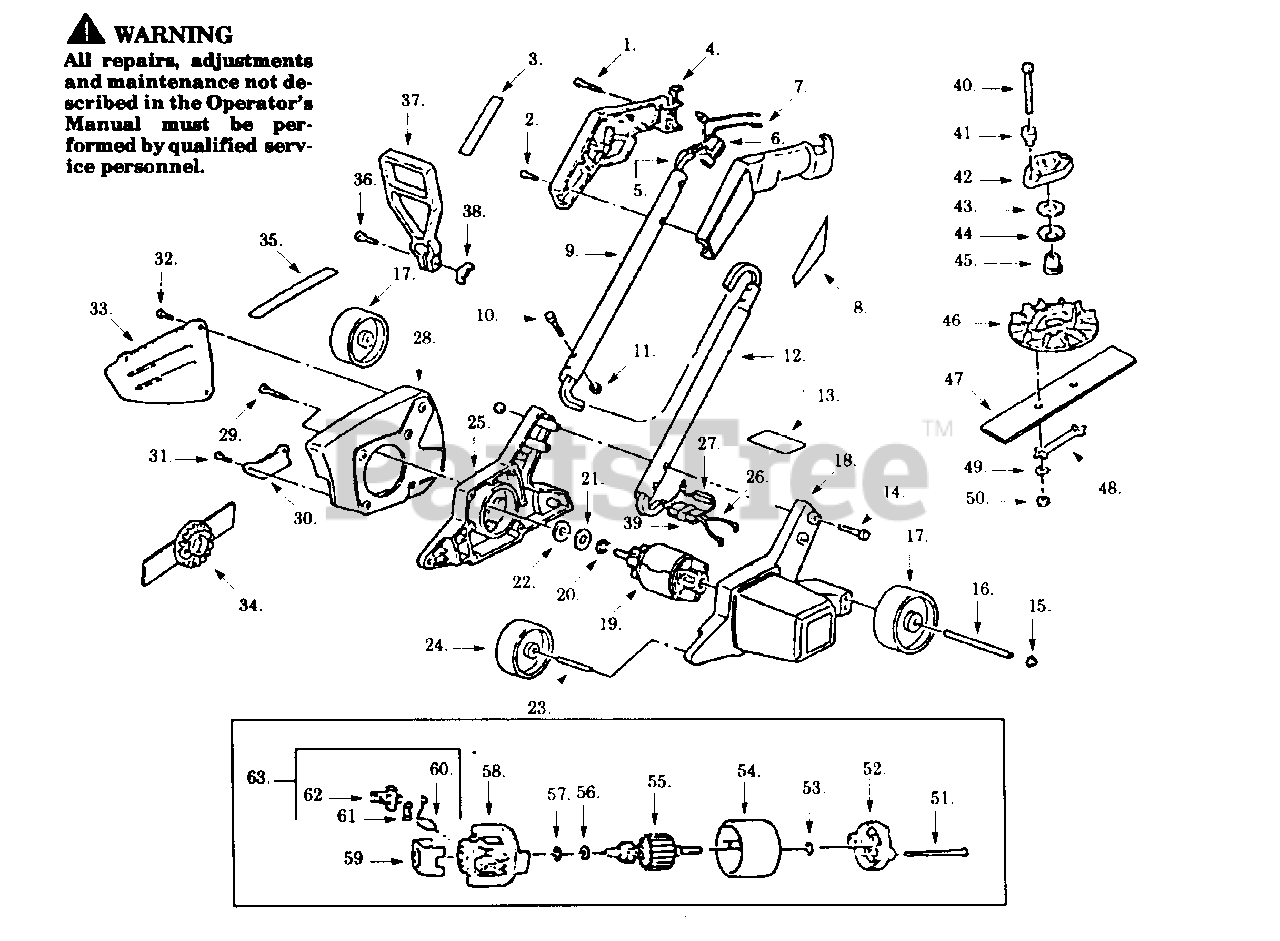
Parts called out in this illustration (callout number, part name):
3	Handle Label
4	Handle Set
5	Harness Ass'y.
6	Trigger Switch
7	Wire Blade Ass'y.
8	Warning Label (Not a serviceable part)
9	Upper Tube
12	Lower Tube
13	Housing Label
16	Rear Axle
17	Rear Wheel
18	Motor Cover
19	Motor Ass'y.
20	Retaining Ring
23	Front Axle
24	Front Wheel
26	P.C. Board Ass'y.
27	Resister
28	Housing Guard
30	Blade Guide
33	Blade Guard
34	Blade Ass'y.
35	Brake Label (Not a serviceable part)
37	Assist Handle
38	Wing Nut
41	Insulating Sleeve
42	Clutch Plate
44	Spring Washer
45	Clutch Sleeve
48	Lock Strap
49	Lockwasher
52	Endbell Ass'y. (Drive)
54	Field Ass'y.
55	Armature Ass'y.
58	Endbell Ass'y. (Brush)
59	Insulator
60	Carbon Brush
61	Spring Brush
62	Brush Holder
63	Brush Kit (Incl. 60,61,62)
